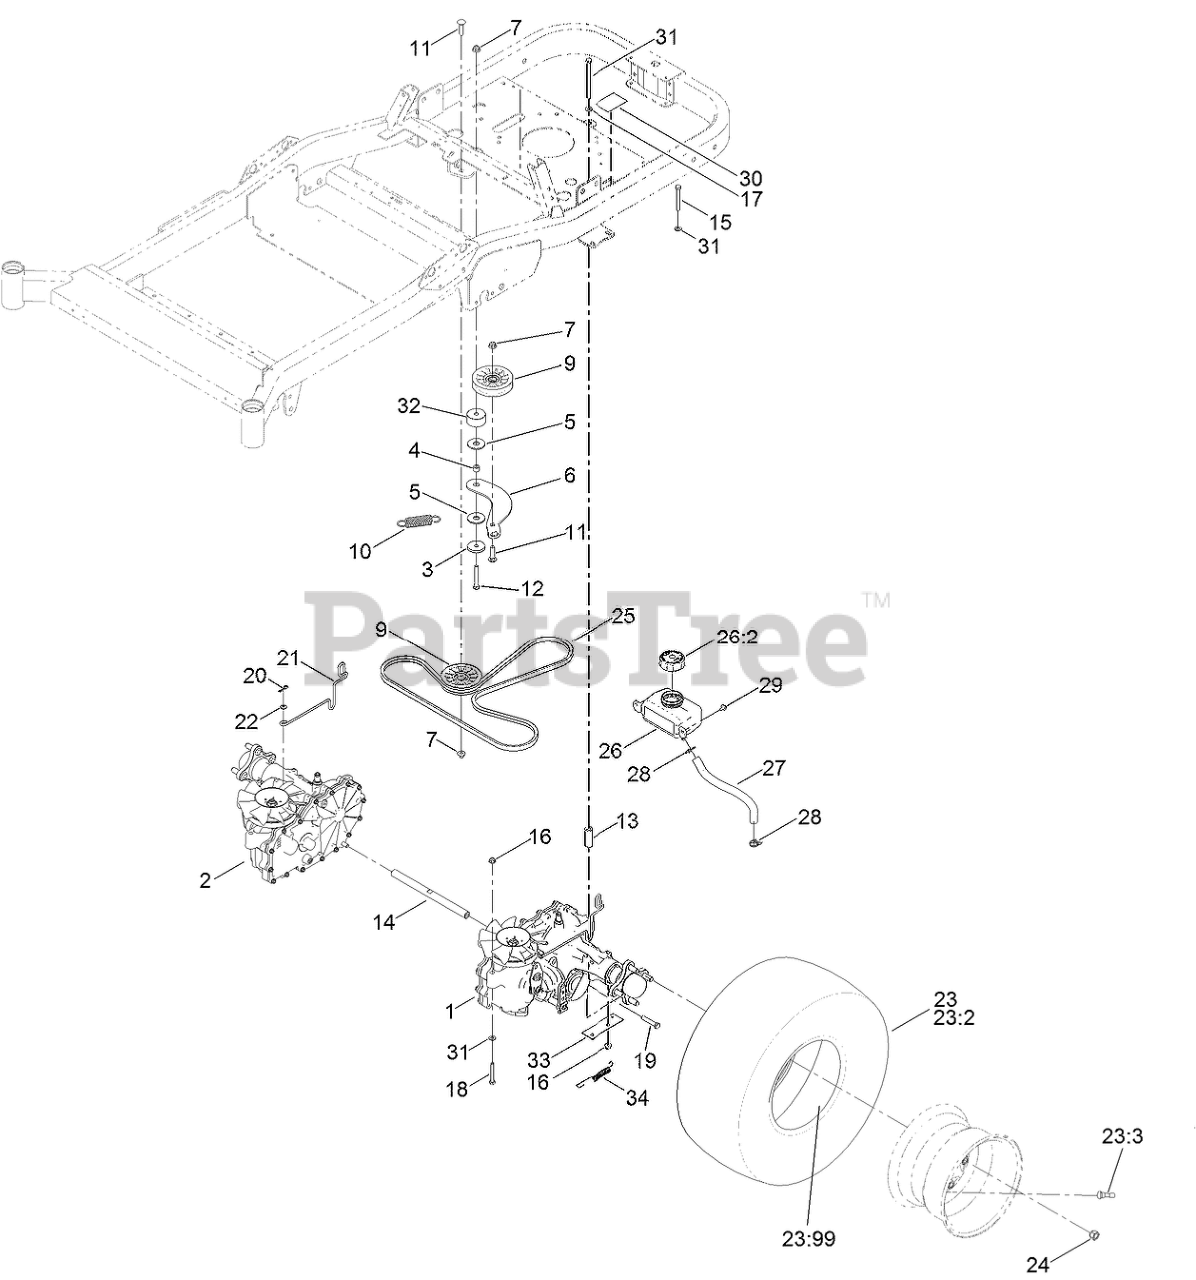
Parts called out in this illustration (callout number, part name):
1	LH HYDRO TRANSMISSION ASM
2	RH HYDRO TRANSMISSION ASM
3	WASHER-PLAIN
4	SPACER
5	WASHER-FRICTION, COMPOSITE
6	ARM-IDLER
7	NUT-HF, NI
9	PULLEY-IDLER, FLAT
10	SPRING-EXTENSION
11	SCREW-CARR
12	SCREW-HH
13	SPACER-HYDRO
14	SHAFT-CROSS, HYDRO
15	SCREW-HH
16	NUT-HF, NI
17	SCREW-HH
18	SCREW-HH
19	SCREW-HH
20	PIN-COTTER
21	ROD-BYPASS
22	WASHER
23	TIRE AND WHEEL ASM
23:3	STEM-VALVE
23:99	Tube-Inner
24	NUT-LUG
25	V-BELT
26	HYD RESERVIOR ASM
26:2	CAP-RESERVOIR, HYD
27	HOSE-OVERFLOW
28	CLAMP-HOSE
29	SCREW-HHFTF
30	DECAL-BYPASS
31	WASHER-PLAIN
32	SPACER
33	PLATE-SPRING
34	SPRING-EXTENSION
